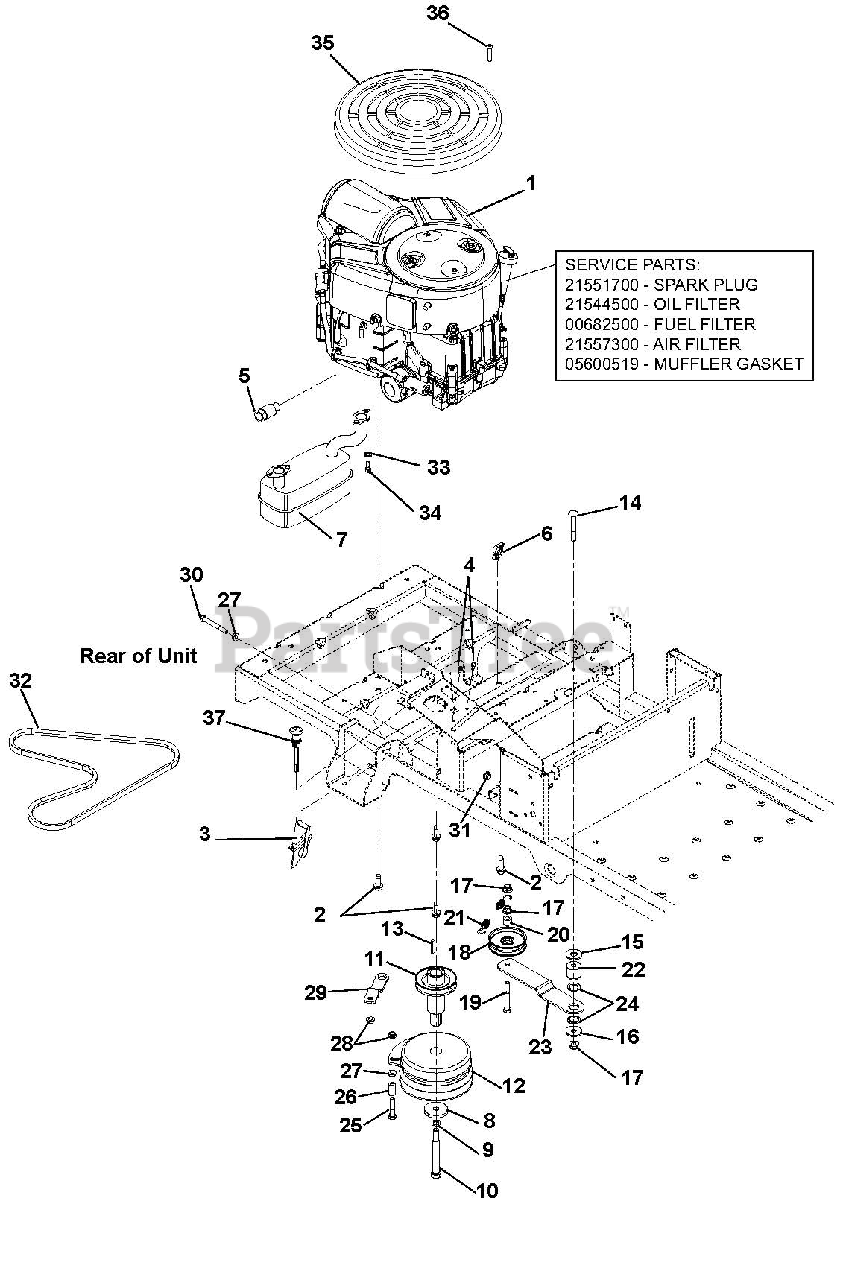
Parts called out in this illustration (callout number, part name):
1	ENGINE, 18HP V-TWIN CE
1	PLUG, BRIGGS SPARK
1	FILTER, OIL
1	GASOLINE FILTER, BRIGGS
1	AIR CLEANER
1	GASKET, MUFFLER BRIGGS 690970
2	SCR,TAP .375-16X1.25HWH TR ZCC
3	CABLE, THROTTLE
4	SCR,TAP #10-24X.50 HWH TR ZCC
5	DRAIN, OIL
6	WIRE CLIP
7	MUFFLER - TWIN BRIGGS
8	WSHR, FLT .469X2.00X.250 ZCC
9	WSHR, LK-REG .438X.109 ZCC
10	BLT, HEX .44-20X4.50 G8 ZCC
11	WLDMT, CRANKSHAFT EXTENSION
12	CLUTCH, 105 FT*LB MONO POLE
13	KEY-SQ .25 X 1.25 X .25 SAE
14	BLT, RHSN .38-16X2.75 G5 ZCC
15	WSHR,FLT .563X1.375X.109 ZCC
16	WSHR,FLT .406X1.375X.135 ZCC
17	NUT,NYL-FLG .38-16 GF ZCC
18	PULLEY, ENGINE CLUTCH 03608
19	BLT, HEX .38-16X2.75 G5 ZCC
20	BSHG-SLV .391X.688X.52 PM
21	SPRING, EXTENSION
22	SPACER, GROUND DRIVE IDLER
23	IDLER ARM, GROUND DRIVE
24	BUSHING, IDLER ARM
25	BLT, HEX .31-18X2.00 G5 ZCC
26	SPACER, RUBBER 5/16 IDX1.0 LG
27	NUT,SPNLK-FLG .31-18 G5 ZCC
28	NUT-LK-TOP-FLG .312-18 GF ZCC
29	BRKT, CLUTCH STOP
30	BLT, HEX .31-18X2.75 G5 ZCC
31	NUT,LK-NYL-FLG .31-18 G5ZC120
32	V-BELT, HA-RAW EDGE
33	WSHR,LK-REG .312X.078 ZCC
34	SCR-CAP .31-18X.88 S/HD G8 ZCC
35	GUARD, BRIGGS ENGINE
36	SCREW, 8-16X.87 PHPAN 3 LOBE
37	CABLE, CHOKE (SNAP IN)
